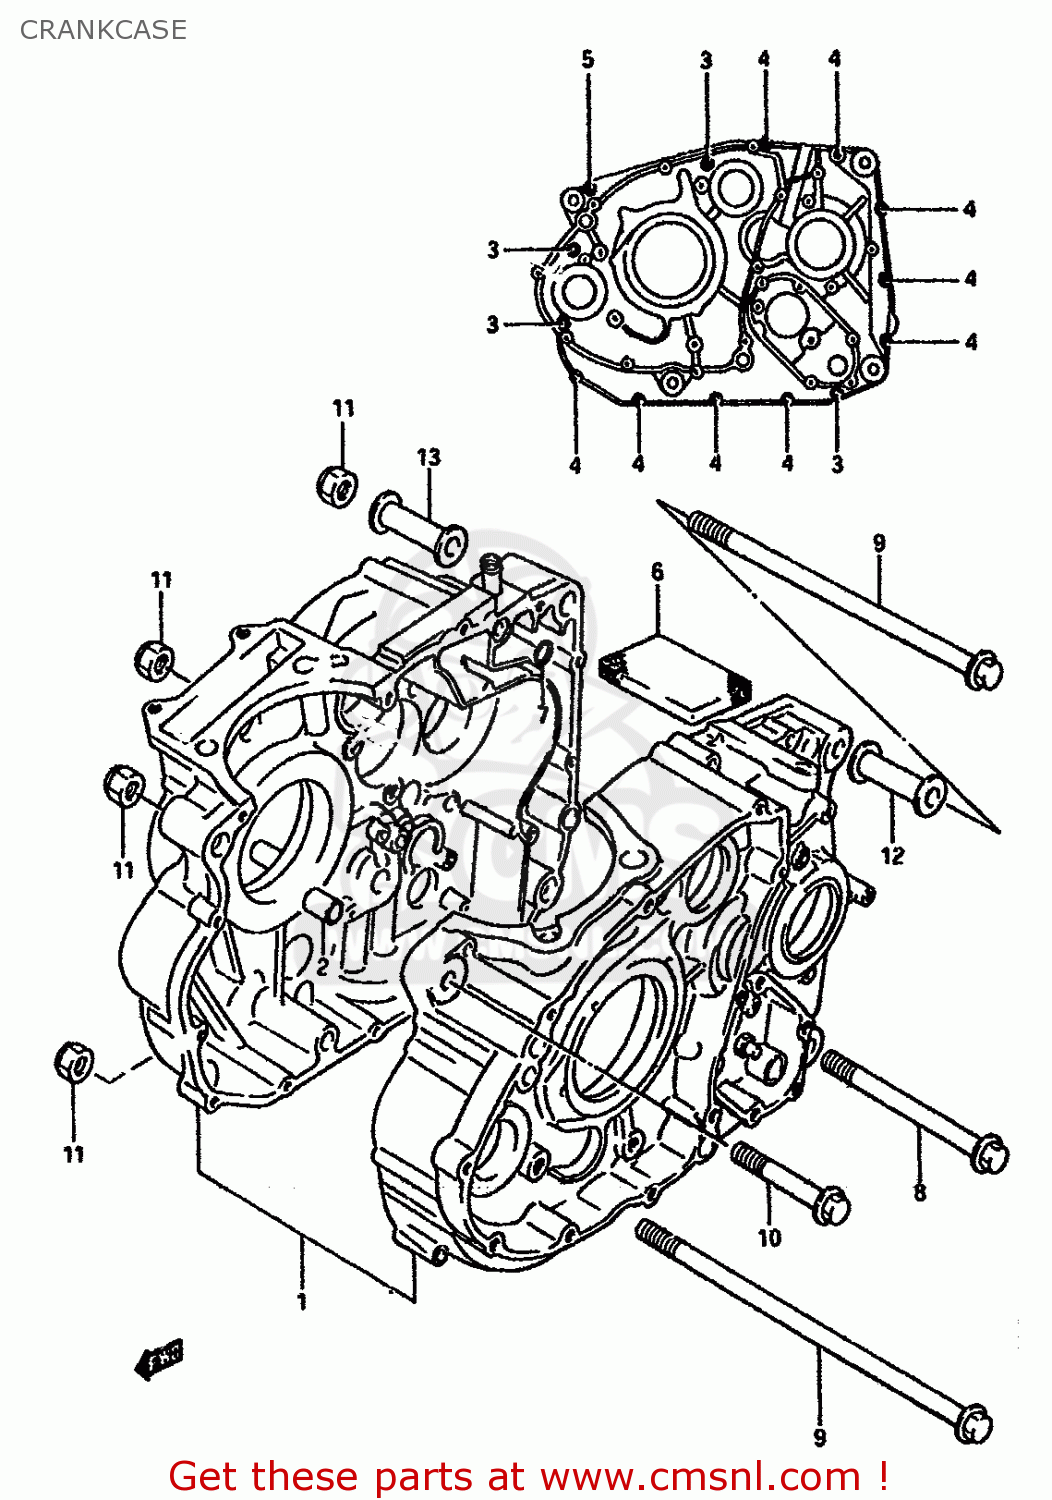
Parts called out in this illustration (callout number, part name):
1	CRANKCASE SET
2	PIN
3	BOLT (6X60)
4	BOLT 6X40
5	BOLT 6X30
6	HOSE
7	O-RING
8	BOLT(10X125)
9	BOLT
10	BOLT
11	NUT
12	SPACER,ENG MTG(L:55)
13	SPACER,ENG MTG,R(L:60)
